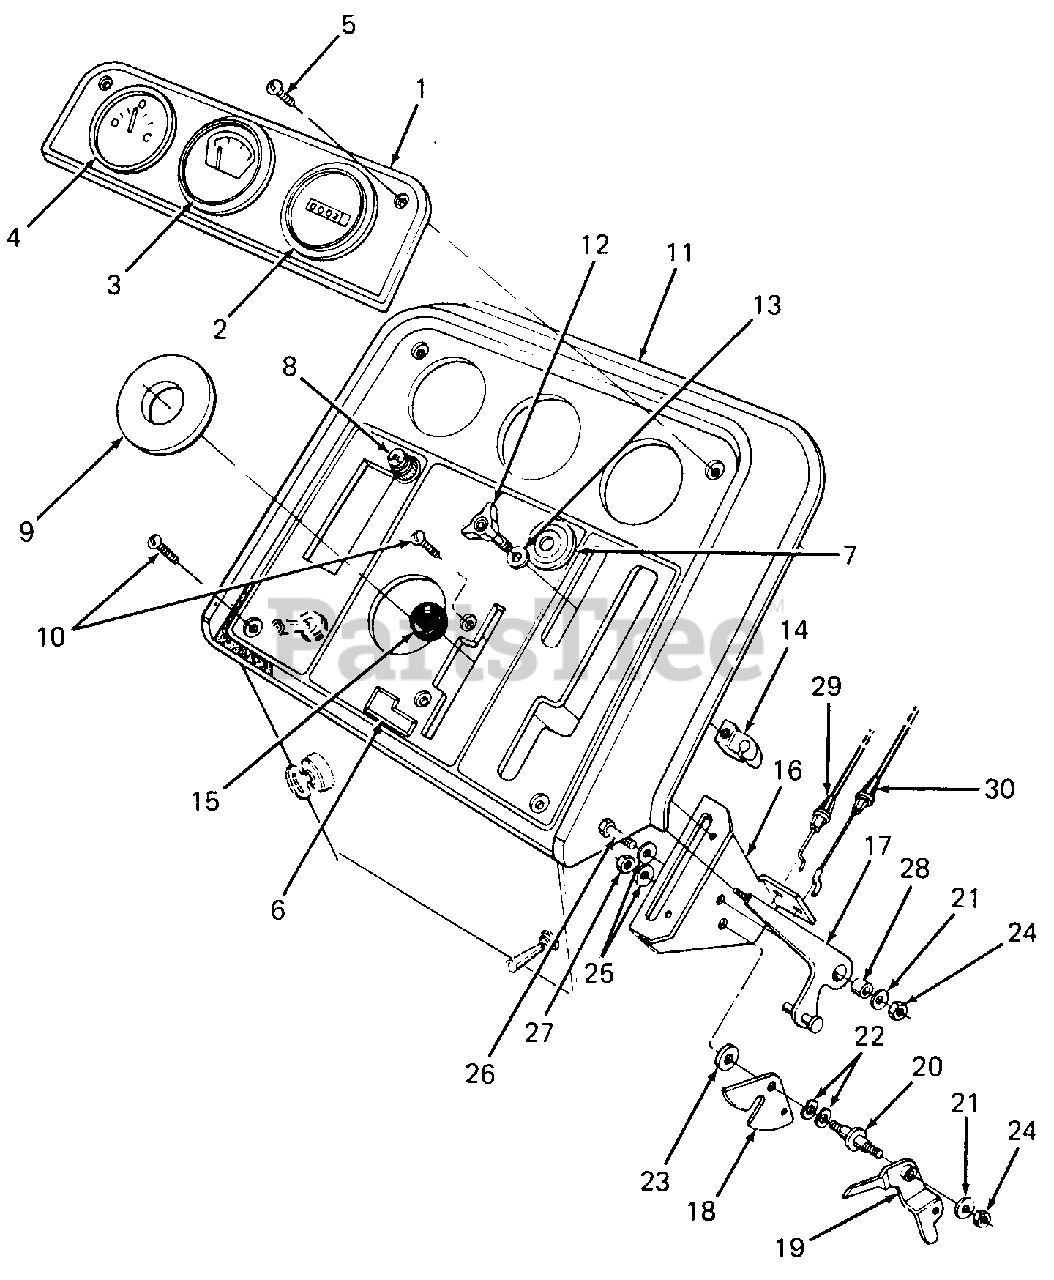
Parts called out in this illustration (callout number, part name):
1	Cover, Panel
2	Hourmeter
3	Gauge, Water Temperature
4	Ammeter
5	Screw, Pan Hd Cutting, #10-24 X 1.5 Lg
6	Plate, Throttle Adhesive, Locktite #495
7	Indicator, Glow Plug
8	Light, Oil Indicator
9	Grommet, Instrument Panel
10	Screw, Pan Hd Cutting, #10-24 X .75 Lg
11	Panel, Instrument
13	Washer, Flat, .266 X .625 X .036 Thk
14	Stop, Handle Detent
15	Knob, Ball
16	Bracket, Throttle Control Support
17	Lever, Throttle Control
18	Cam, Throttle Control
19	Cam, Fuel Shut-Off
20	Shaft, Pivot
21	Washer, Flat, .344 X .62 X .063 Thk
22	Washer, Spring, .39 X .74 X .020 Thk
23	Disc, Friction
24	Nut, Hex Center Lock, 5/16-18 GR5
25	Washer, Bell, .345 X .88 X .060
26	Screw, Hex Cap, 5/16-18 X 1.0 Lg GR5
27	Nut, Hex, 5/16-18
28	Spacer, Tube, .325 X .43 X .45 Lg
29	Cable, Throttle
30	Cable, Shut-Off
